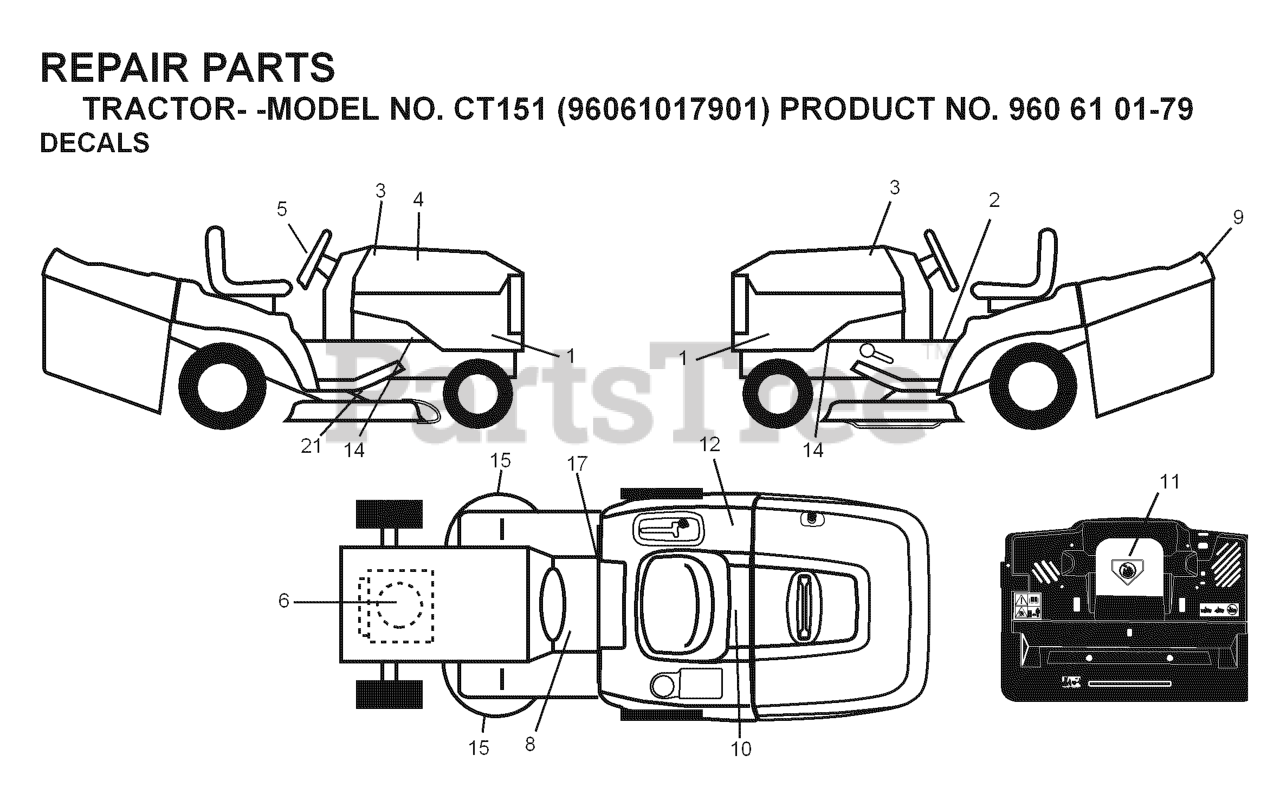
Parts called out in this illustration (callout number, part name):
2	LABEL
3	DECAL.HOOD.NAMELOGO.HUSQ
5	DECAL.WHEEL.STRG.LGN.H
6	DECAL
8	DECAL
9	DECAL.HOOD.NAMELOGO.HUSQ
10	DECAL BTRY SYMBOLS
11	DECAL.INTERNATIONL.CUTFINGER
12	Decal, Fender 100 DB/CE
17	DECAL PARK BRAKE
